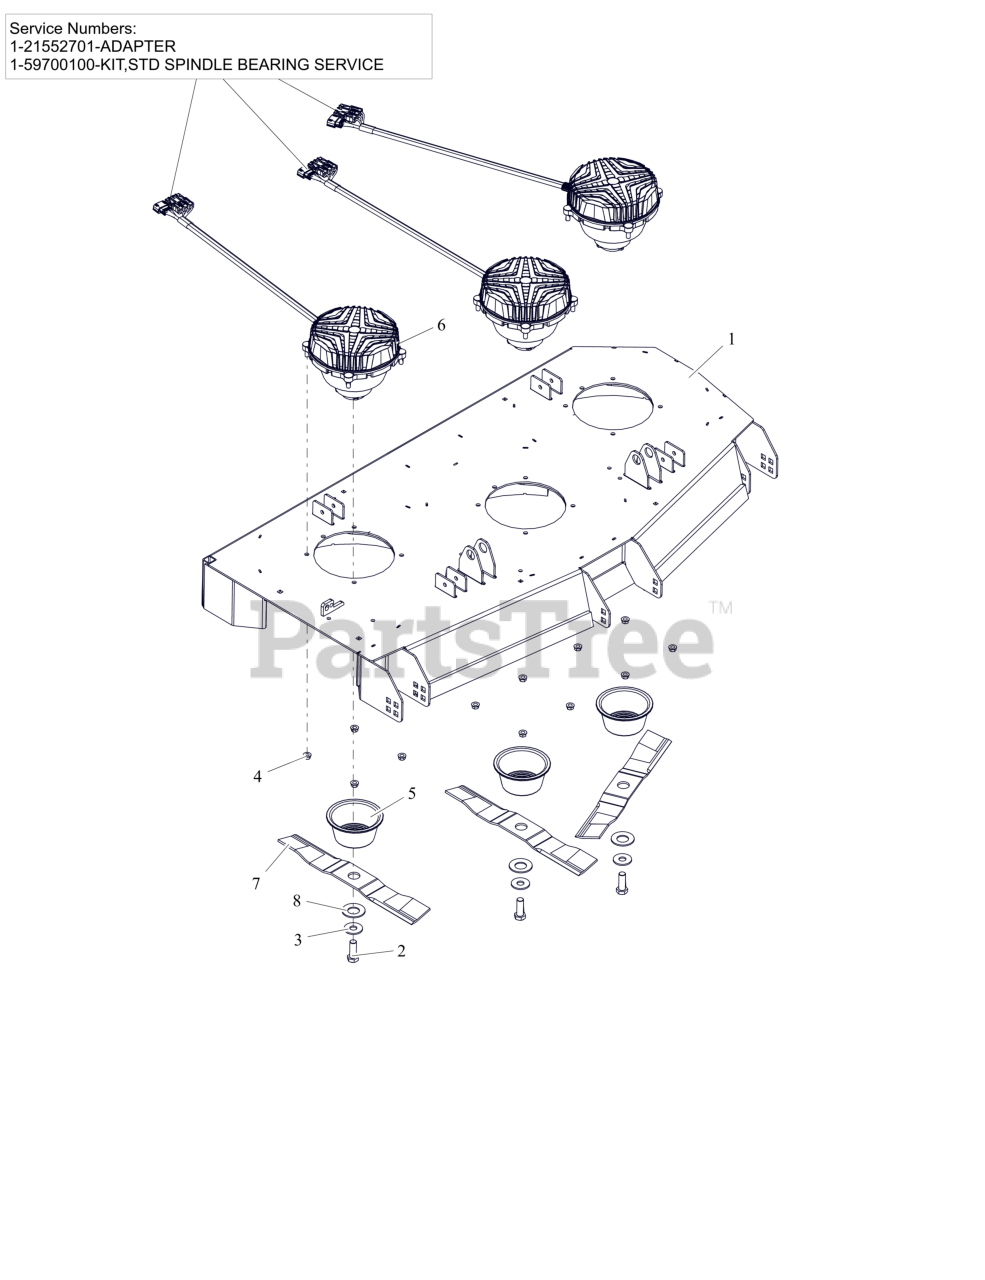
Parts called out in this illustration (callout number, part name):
1	KIT,DECK 52 SD W/DECALS-G
2	BLT, HEX .62-18X1.75 G8 ZCC
3	WSHR, HRDN 0.687X1.75X0.134 HRD
4	NUT-LK-CTR-FLG .375-16 GF ZCC
5	GUARD, SPINDLE LOWER
6	MOTOR, DECK - 48"/52" CW
6	ADAPTER
6	KIT, STD SPINDLE BEARING SERVICE
7	BLADE, MOWER - 18.00" EFF CW
8	WSHR, BLVL - .56X28.5X3 PHOS.COAT
